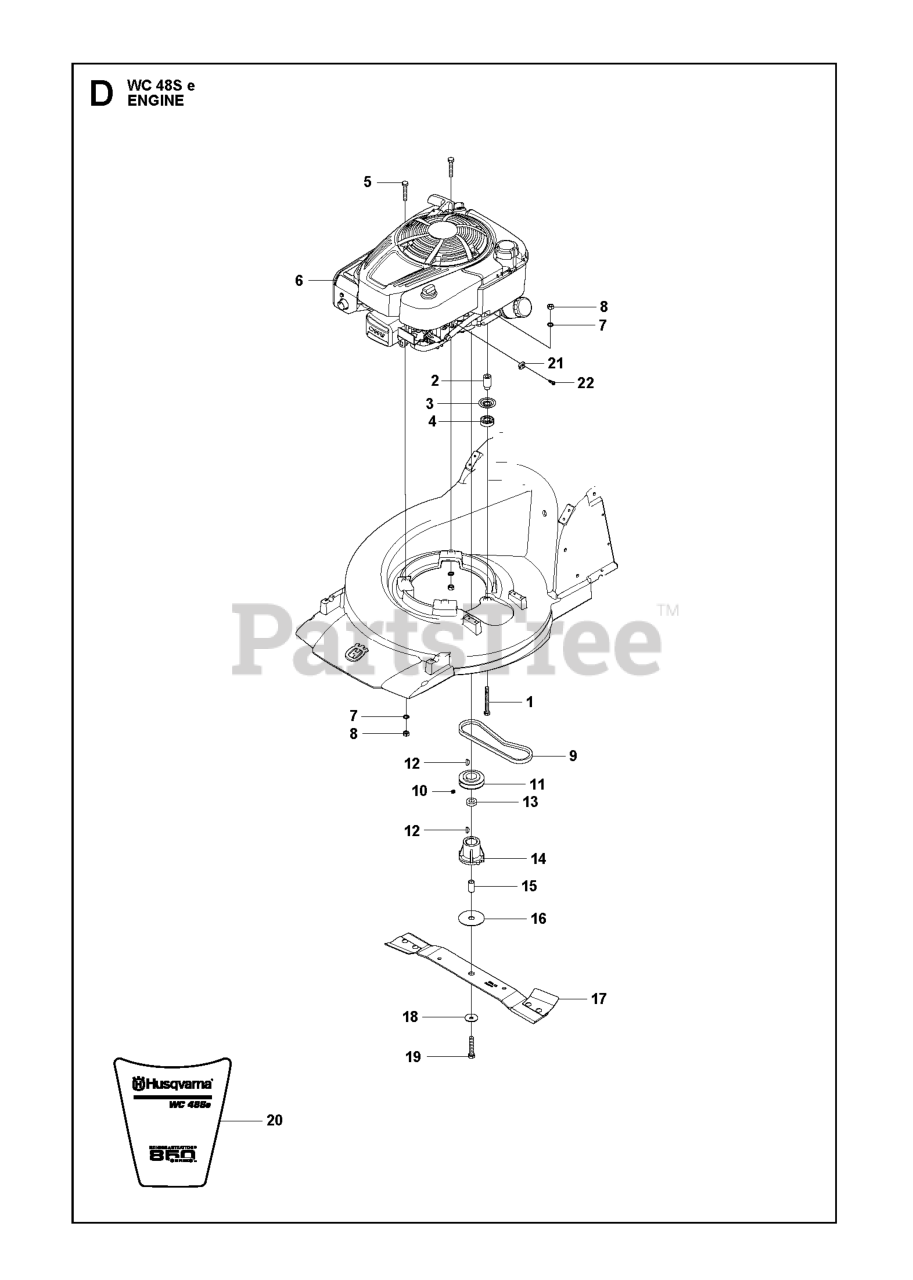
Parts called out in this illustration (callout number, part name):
1	Screw, Ehhm
5	SCREW
8	NUT
